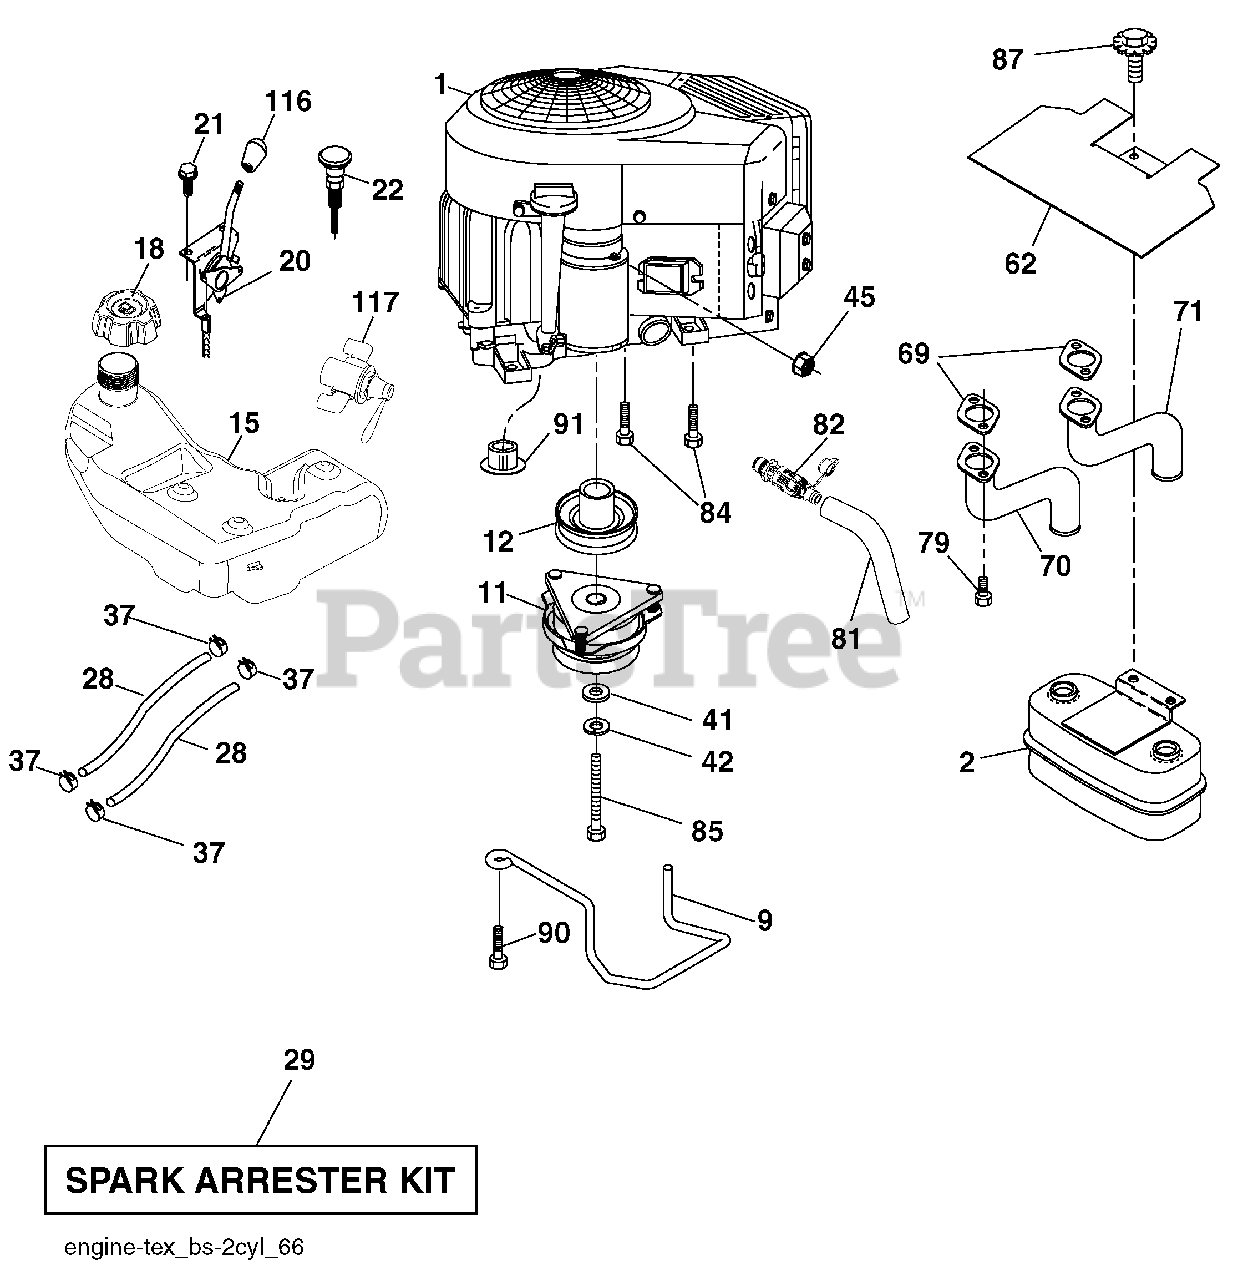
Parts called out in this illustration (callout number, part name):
9	Keeper Belt Engine
11	Clutch Electric
12	Pulley Engine
18	Cap Asm
20	Control Throttle
21	Screw #10 x .750 BOS Thread
22	Control Choke Ergo
28	Fuel Line
29	Spark Arrester Kit
37	Clamp Hose
41	Washer 1-1/2 OD x 15/32 ID x .250
42	Washer Lock 7/16
45	Nut Keps Hex 1/4-20 unc
62	Heat Shield
70	Exhaust Tube LH
71	Exhaust Tube RH
81	Tube Drain Oil Easy
82	Valve Oil Drain
84	Screw 3/8-16 x 1-1/4
85	Bolt Hex 7/16-20 x 4 x Gr. 5-1.5 Thr
87	Bolt 5/16-18 unc x 3/4 w/Sems
90	Screw 3/8-16 x 1
91	Bushing 1.375 OD
116	Knob Soft Touch
117	Valve Fuel Reserve
